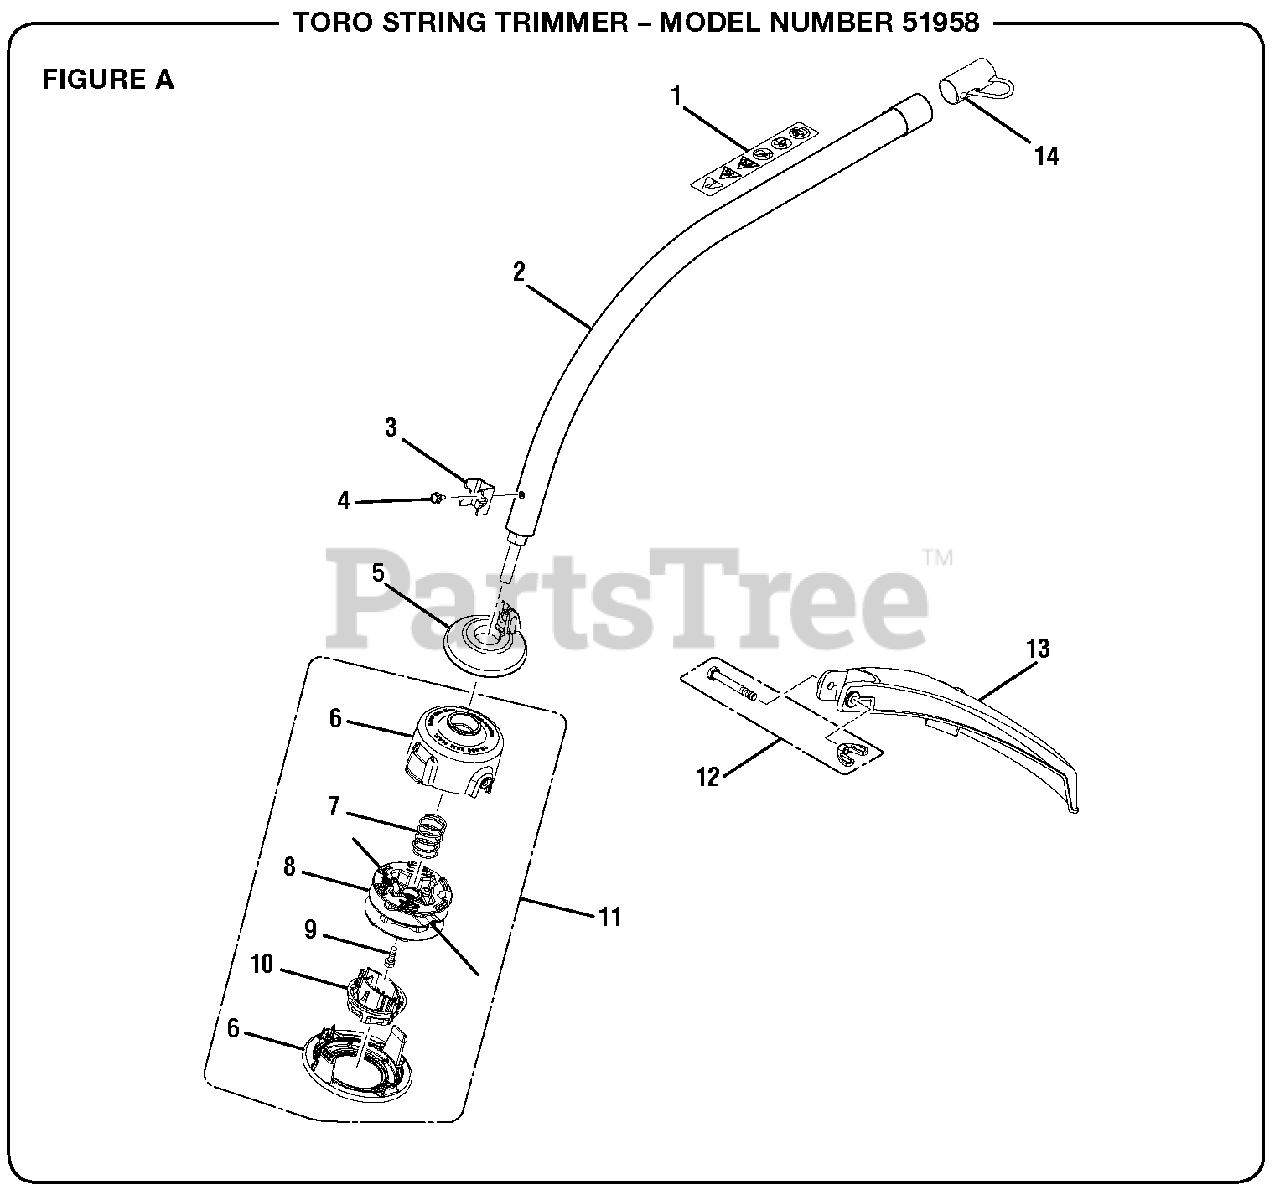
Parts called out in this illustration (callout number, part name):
1	Warning Label
2	Curved Shaft Assembly
4	Screw (#10-32 x 3/8 in., Hex Washer Hd.)
5	Grass Shield
6	Stringhead Housing
7	Compression Spring
8	Spool
9	Bolt (5/16-18 x 1/2 in.)
10	Bump Knob
11	Trimmer Head Assembly (.095)
12	Fastener Parts Kit
13	Guard
14	Hanger Cap
